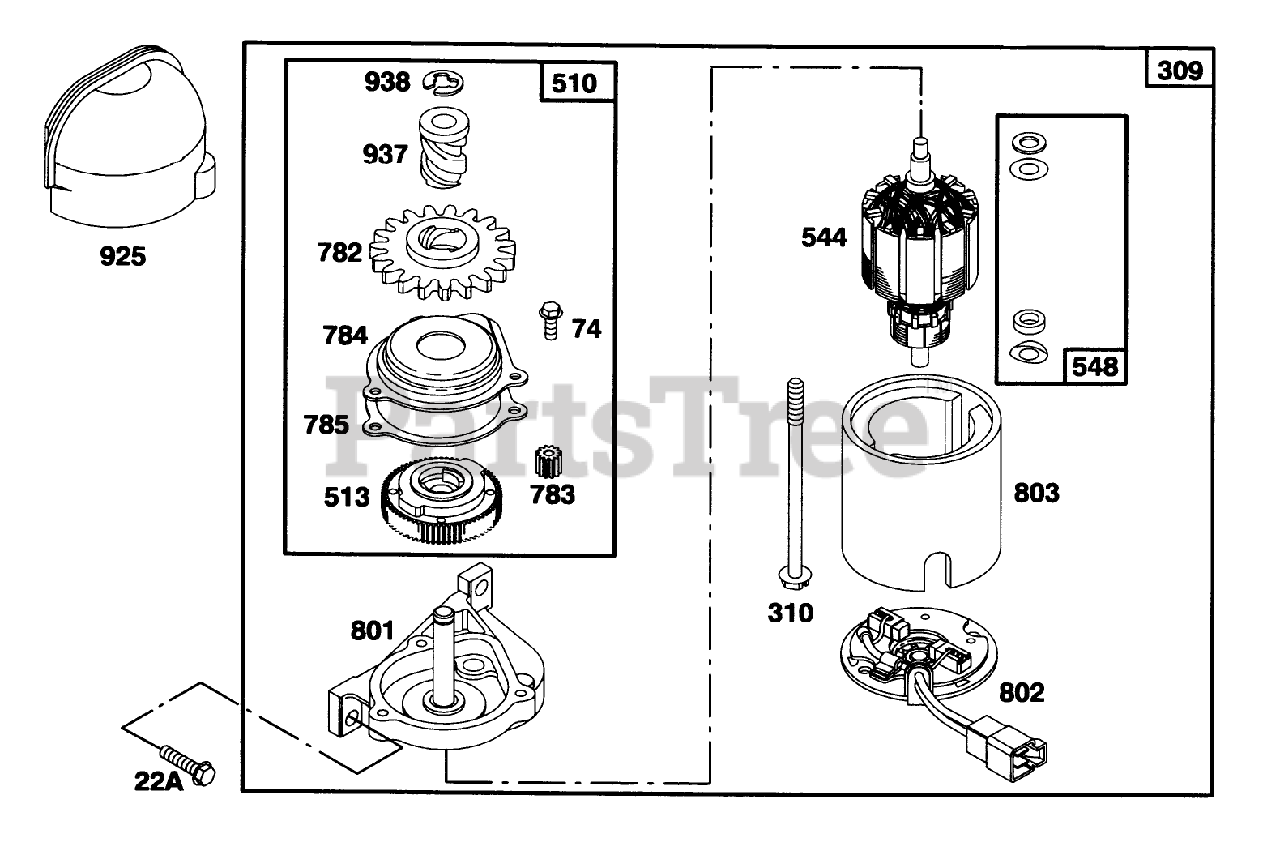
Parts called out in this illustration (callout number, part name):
22A	SCREW - CARBUERTOR MTG
74	SCREW - SEM
510	DRIVE SET
513	CLUTCH - STARTER
548	WASHER ASSEMBLY
782	GEAR - STARTER
925	COVER - STARTER
938	RETAINER - LOCK
